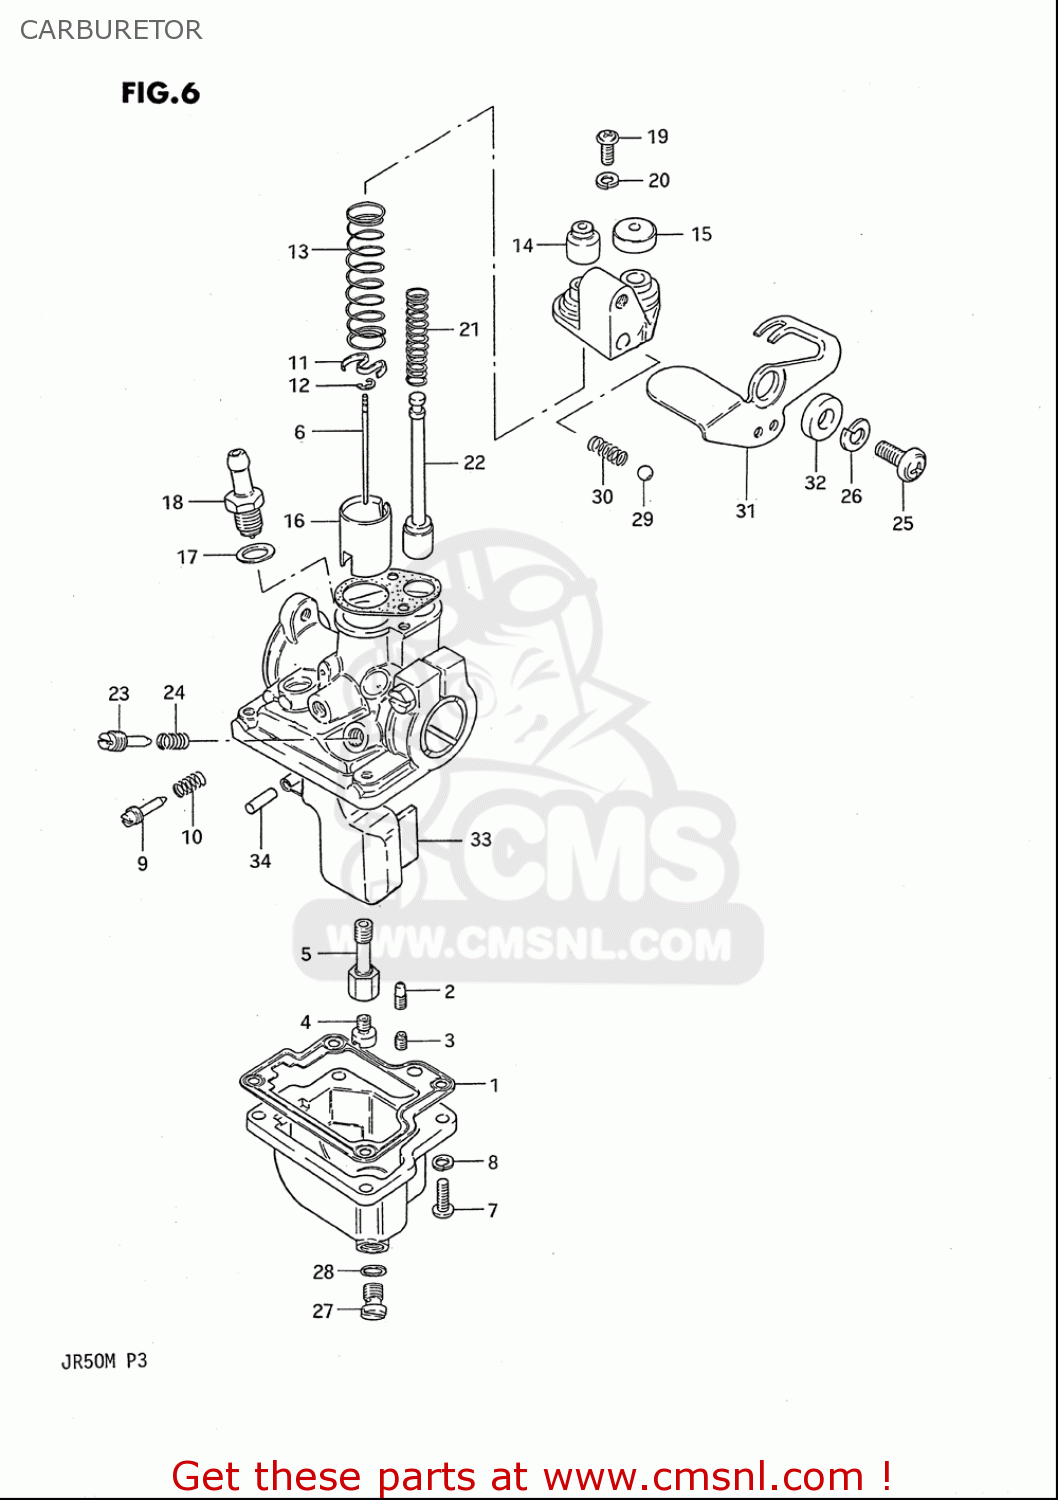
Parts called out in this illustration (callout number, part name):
1	GASKET,FLOAT CAHMBER (NAS)
2	JET,PILOT(15)
3	JET,PILOT
4	JET,MAIN
5	JET,NEEDLE
6	NEEDLE,JET
7	SCREW
8	WASHER,LOCK
9	SCREW,THROTTLE STOP
10	SPRING
11	SEAT,THROTTLE VALVE SPRING
12	CLIP,NEEDLE
13	SPRING,THROTTLE VALVE
14	CAP
15	RUBBER,THROTTLE VALVE CAP
16	VALVE,THROTTLE
17	GASKET,THRO VALVE INSPECTION (NAS)
18	VALVE ASSY,NEEDLE
19	SCREW
20	WASHER,LOCK
21	SPRING
22	VALVE,STARTER
23	SCREW,AIR
24	SPRING
25	SCREW
26	WASHER,LOCK
27	PLUG
28	GASKET,DRAIN,PLUG (NAS)
29	BALL,STARTER SHAFT
30	SPRING,STARTER SHAFT
31	LEVER,STARTER
32	RING,CARBURETOR STARTER
33	FLOAT
34	PIN,FLOAT
